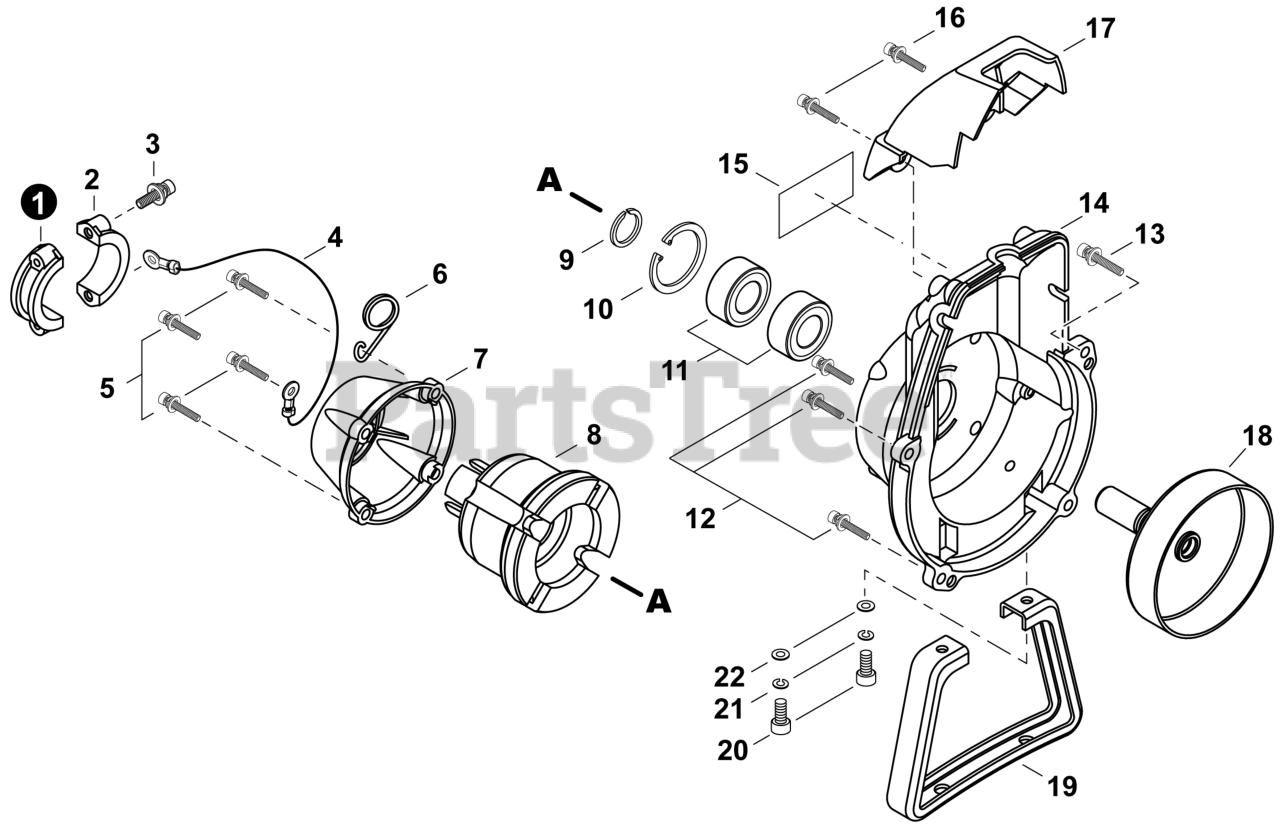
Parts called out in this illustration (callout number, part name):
1	CLAMP - A
2	CLAMP - B
3	BOLT 5x25
4	LEAD - GROUND
5	BOLT 5x20
6	HOLDER, CABLE
7	CAP, CUSHION
8	CUSHION, AV
9	RING, SNAP
10	RING, SNAP 32
11	BEARING, BALL 6002 DDU
12	BOLT 5x20
13	BOLT M5x30
14	COVER, FAN
15	LABEL - MODEL B452
16	BOLT M4x16
17	GUARD, TOP
18	DRUM, CLUTCH
20	BOLT 5x20 HSH
21	WASHER, SPRING 5
22	WASHER 5.5x12x0.8
